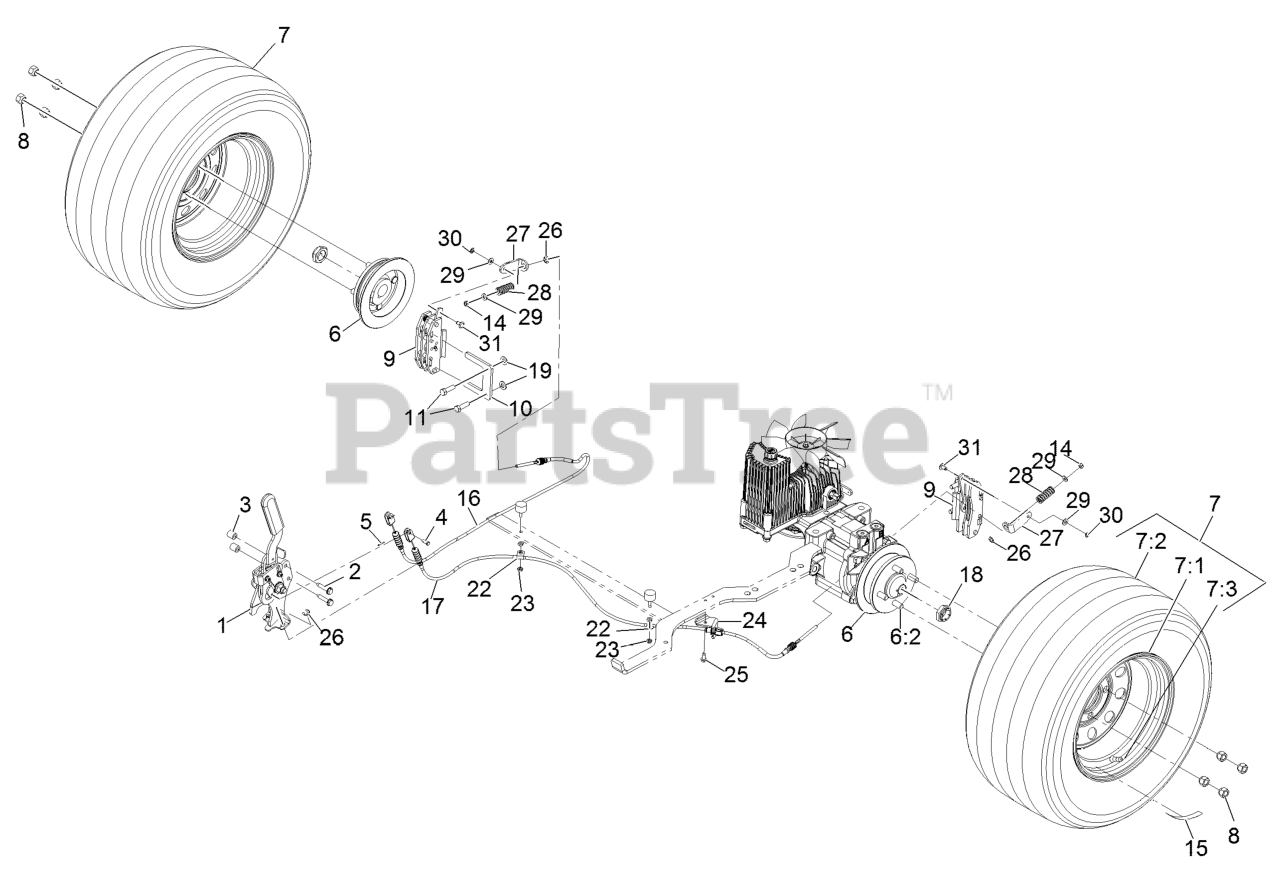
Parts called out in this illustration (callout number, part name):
1	BRAKE HANDLE ASM
4	PIN-CLEVIS
5	PIN-COTTER
6	WHEEL HUB ASM
6:2	STUD-WHEEL
7	WHEEL AND TIRE ASM
7:3	Stem-Valve
8	NUT-LUG
9	CALIPER-BRAKE
10	PLATE-MOUNT, BRAKE
11	SCREW-LOCK, PATCH
14	NUT-LOCK, NI
18	LOCKNUT
19	WASHER-FLAT
23	NUT-LOCK, NI
24	BRACKET-CABLE
25	SCREW-HWH
27	BRACKET-BRAKE, L
28	SPRING-DIE
29	WASHER-FLAT
31	PIN-BRAKE
